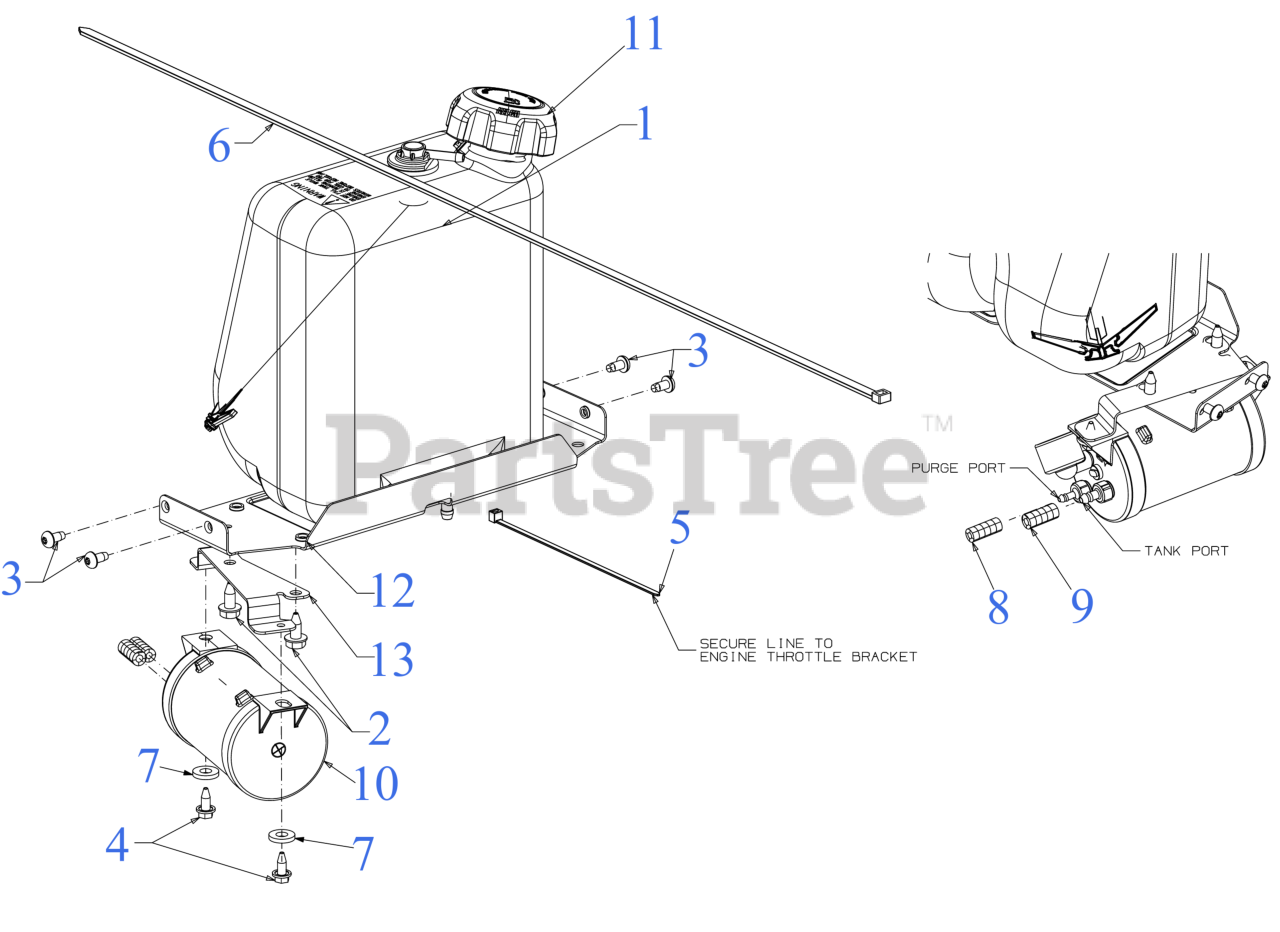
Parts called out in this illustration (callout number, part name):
1	FUEL TANK ASSEMBLY (1.36 Gal)
1	RUBBER GROMMET 23.0 ID x 35.5 OD
1	ROLLOVER FUEL VALVE
2	SCREW 5/16-18 x .750
3	SCREW 1/4-20 x .5
4	SCREW 1/4-20X.625
5	7" CABLE TIE
6	CABLE TIE 36"
7	FLAT WASHER.344X.75X.1
8	FUEL HOSE LO PERMEATION 30"
9	FUEL HOSE LO PERMEATION 28"
10	CARBON CANISTER
11	FUEL CAP (W/TETHER)
